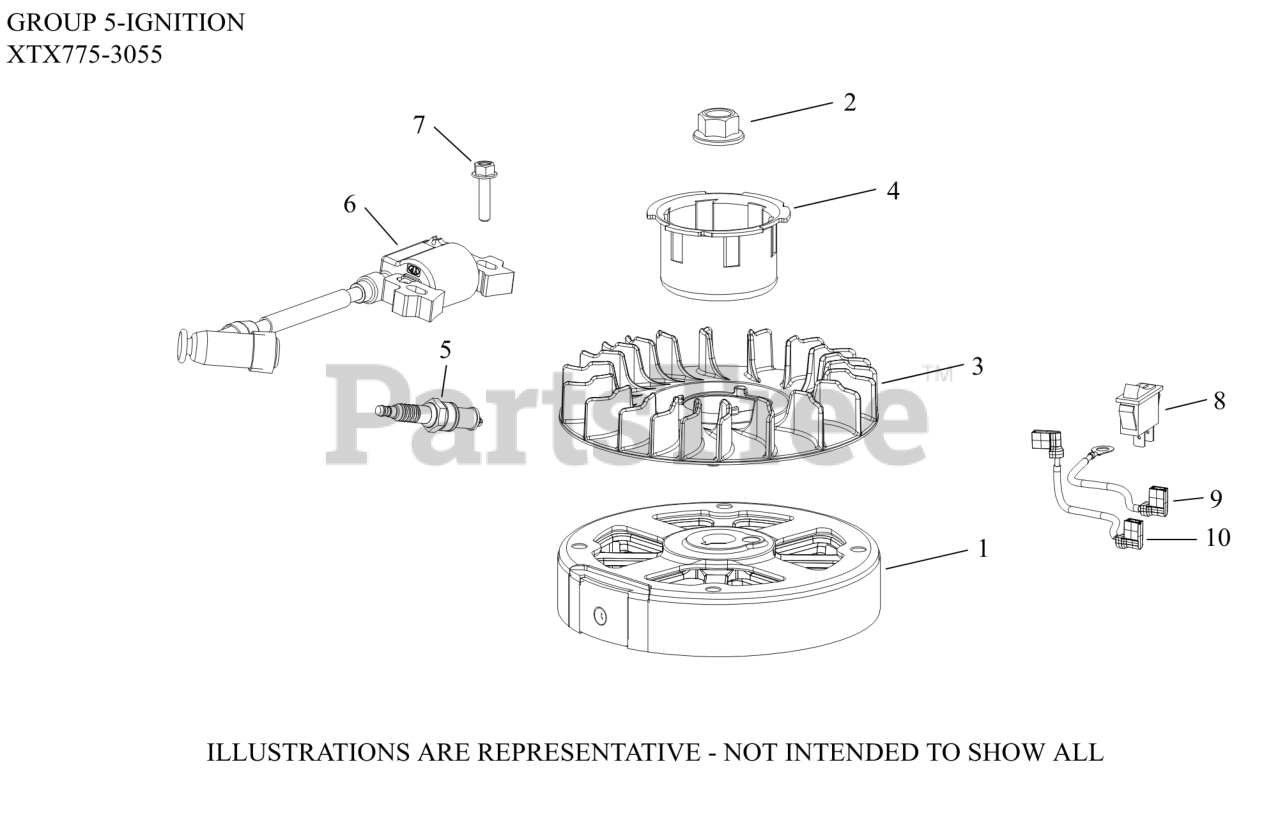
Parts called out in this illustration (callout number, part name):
1	FLYWHEEL (CAST IRON)
2	NUT, FLYWHEEL (W/SERRATIONS)
3	FAN, FLYWHEEL
4	CUP, DRIVE - (#1410905S)
5	PLUG SPARK 12MM RFI
6	MODULE IGN (#1458416S)
7	SCREW, M6 X 25-(#25086436S)
8	SWITCH, ROCKER
9	LEAD,GROUND TO KILL (RCKR SWITCH)
10	LEAD, TOGGLE SWITCH KILL
